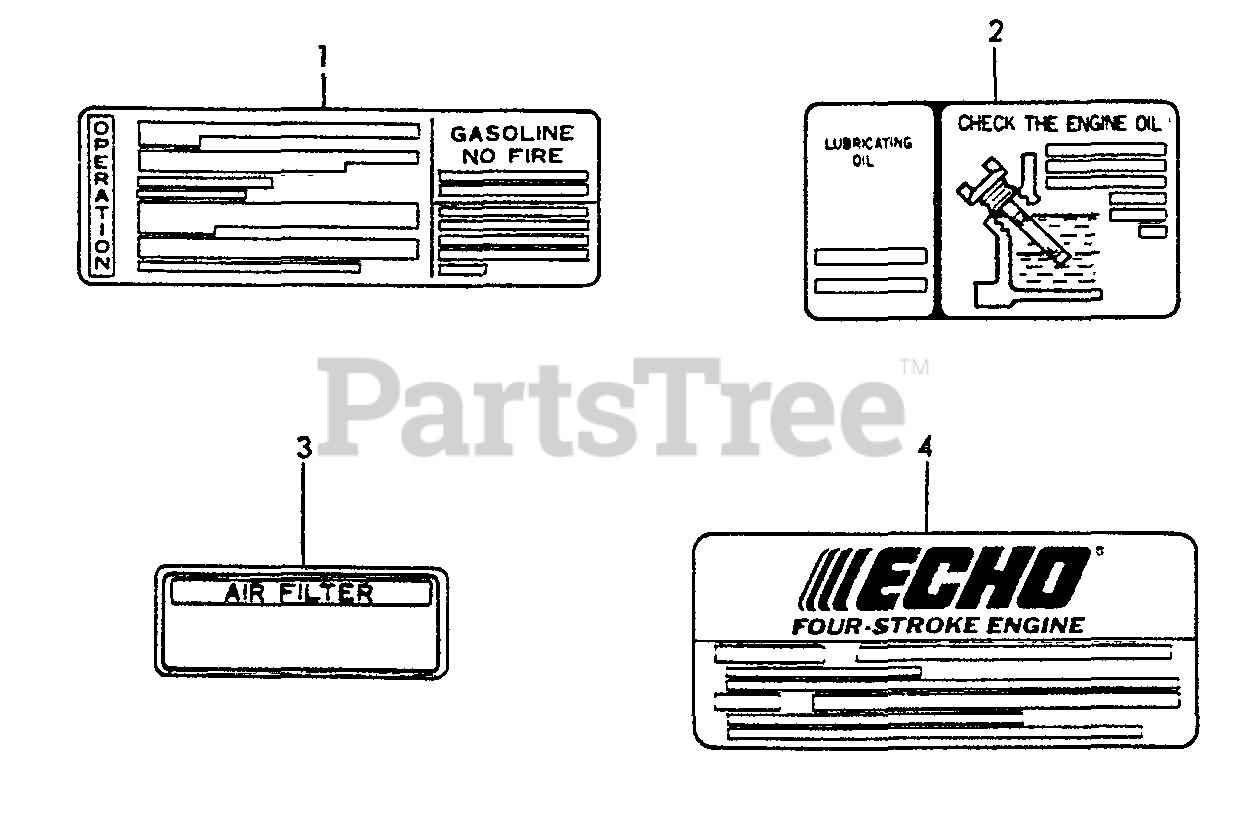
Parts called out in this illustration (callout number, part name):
1	LABEL, OPERATION
2	LABEL, OIL
3	LABEL - AIR FILTER
4	LABEL, ECHO
